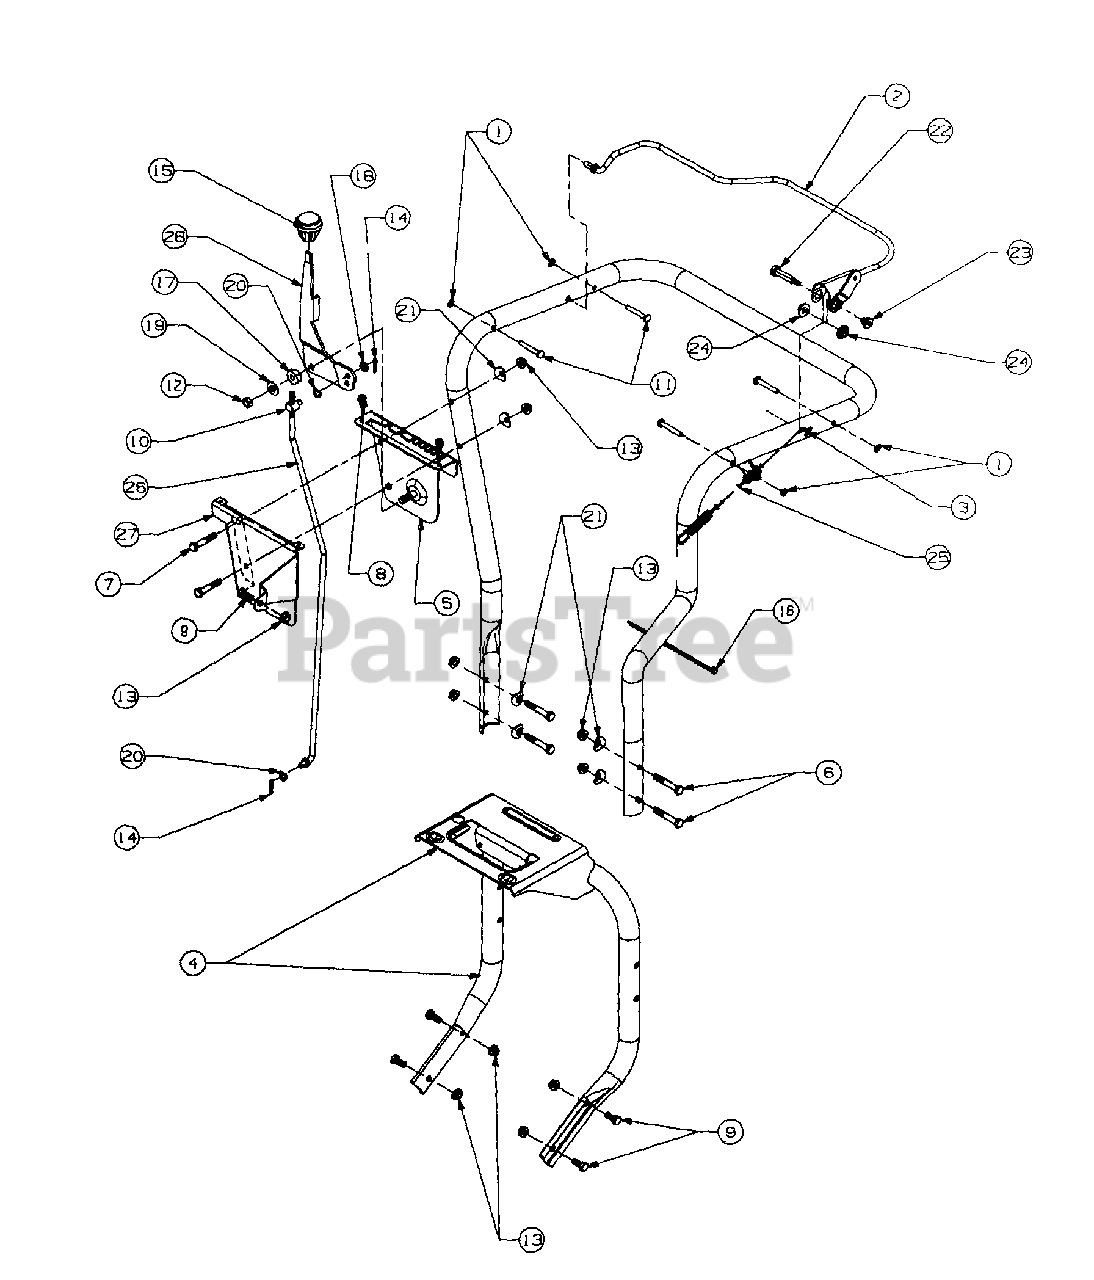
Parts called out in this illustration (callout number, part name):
1	PUSHNUT
7	SCREW-HEX
8	SCREW-HEX
9	SCREW-HEX
10	FERRULE
11	PIN-STUD
12	NUT-HEX LOCK
13	NUT-HEX LOCK
14	PIN-COTTER 2
15	KNOB-SHIFT
16	CABLE TIE
17	WASHER-RUBBER
18	WASHER-FLAT
19	WASHER-FLAT
20	WASHER-SPRING
21	WASHER-SADDLE
22	SCREW-SHOULDER
23	NUT-SHOULDER
24	BEARING-FLANGE PLASTIC
25	CABLE-CLUTCH
26	ROD-SHIFT
